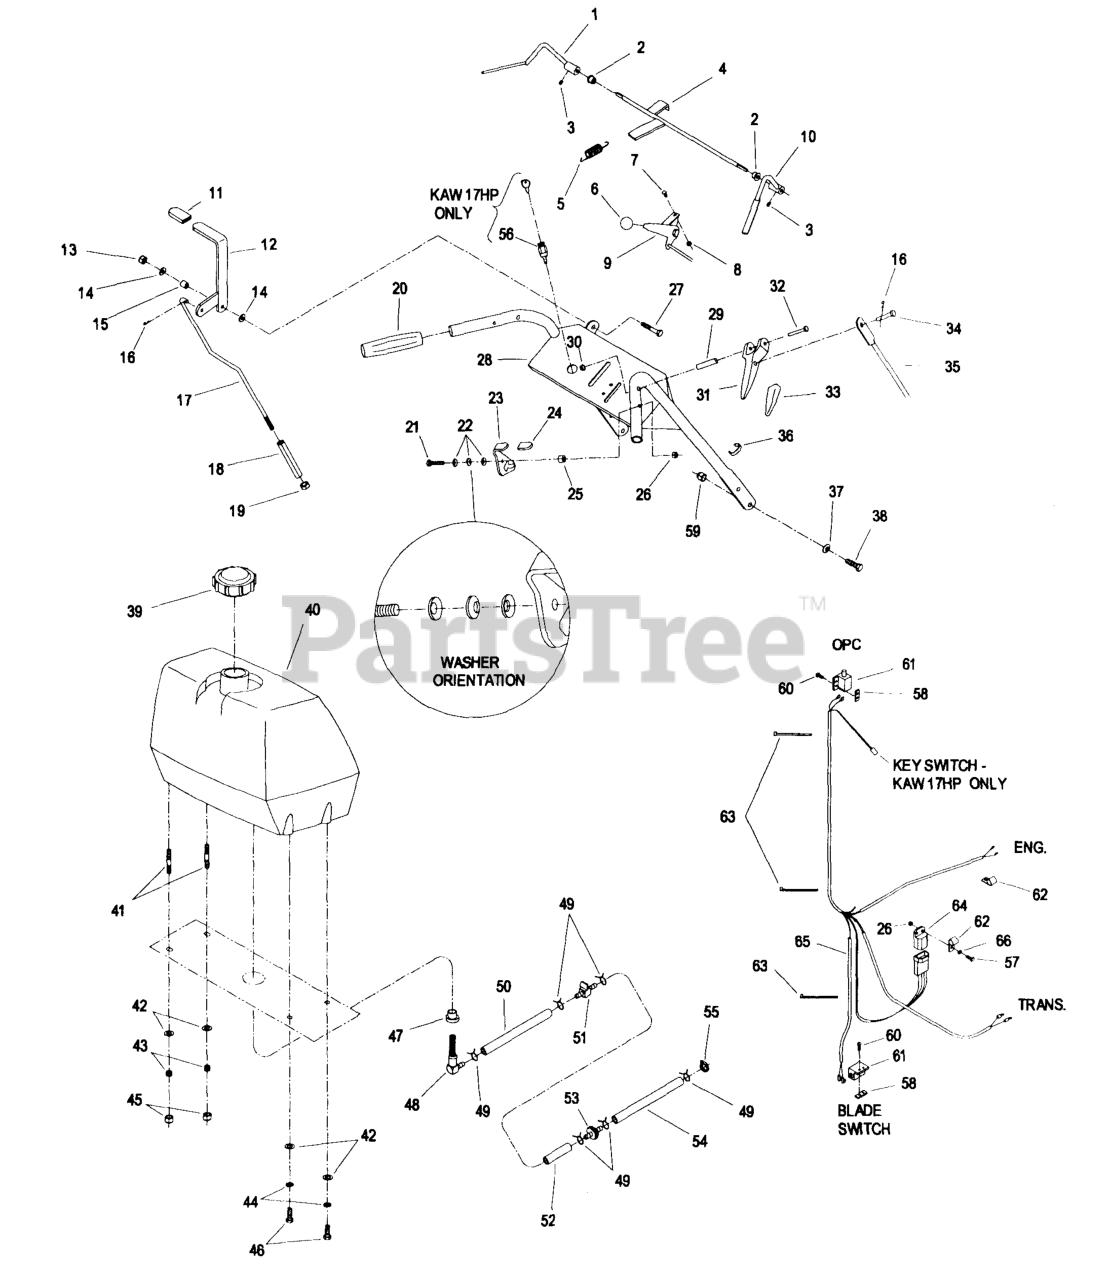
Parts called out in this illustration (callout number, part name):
1	LEVER-LH
2	BUSHING-NYLON
3	SCREW-SET
4	WLD,ROD OPC
5	SPRING-EXTENSION
6	KNOB-BALL
7	BOLT-CARR
9	CABLE,THROTTLE CONTROL
10	LEVER-RH
11	GRIP-LEVER
15	BUSHING-LEVER, LIFT
16	PIN-COTTER
17	LINKAGE,UPPER
18	TURNBUCKLE
22	WASHER-SPRING
24	GRIP-LATCH
29	PIN-ROLL
30	NUT-PUSH
31	DRIVE LEVER ASM
32	PIN-LEVER, DRIVE
33	GRIP-LEVER, DRIVE
34	PIN-CLEVIS
35	LINKAGE,DRIVE WHEEL
36	CLIP-CABLE
39	CAP-FUEL
41	STUD
43	SPRING-TANK, FUEL
44	WASHER-LOCK
48	ELBOW-TANK, FUEL
49	CLAMP
50	HOSE-FUEL
51	VALVE-FUEL
52	HOSE-LINE, FUEL
54	LINE-FUEL
55	CLAMP-HOSE
56	SWITCH & KEY (INCLUDES NU
58	PLATE-TAPPED
61	SWITCH-OPEN, NORMALLY
62	CLIP-LOOM
63	TIE-CABLE
64	MODULE-INTERLOCK
